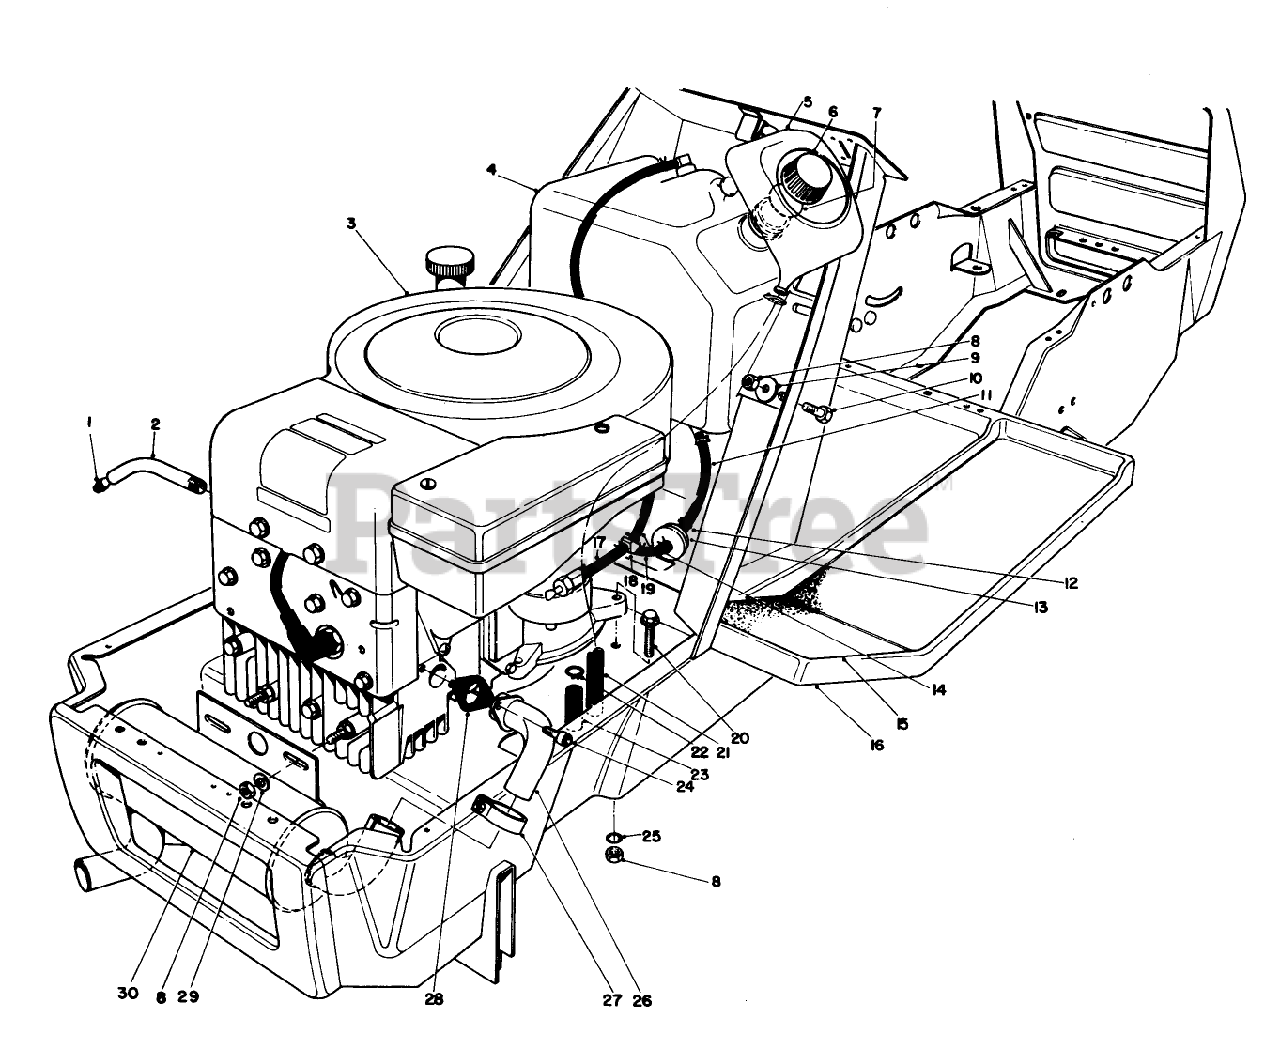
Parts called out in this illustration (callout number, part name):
1	PLUG-PIPE, SQH
3	Engine
5	Funnel-Overflow
8	NUT-LOCK, CONE
10	SCREW-HH
20	SCREW-HH
21	FUNNEL HOSE
24	SCREW-HSH
25	WASHER-LOCK, INTERNAL
28	Exhaust Gasket
29	WASHER-PLAIN
30	EXHAUST MUFFLER 10 HP
